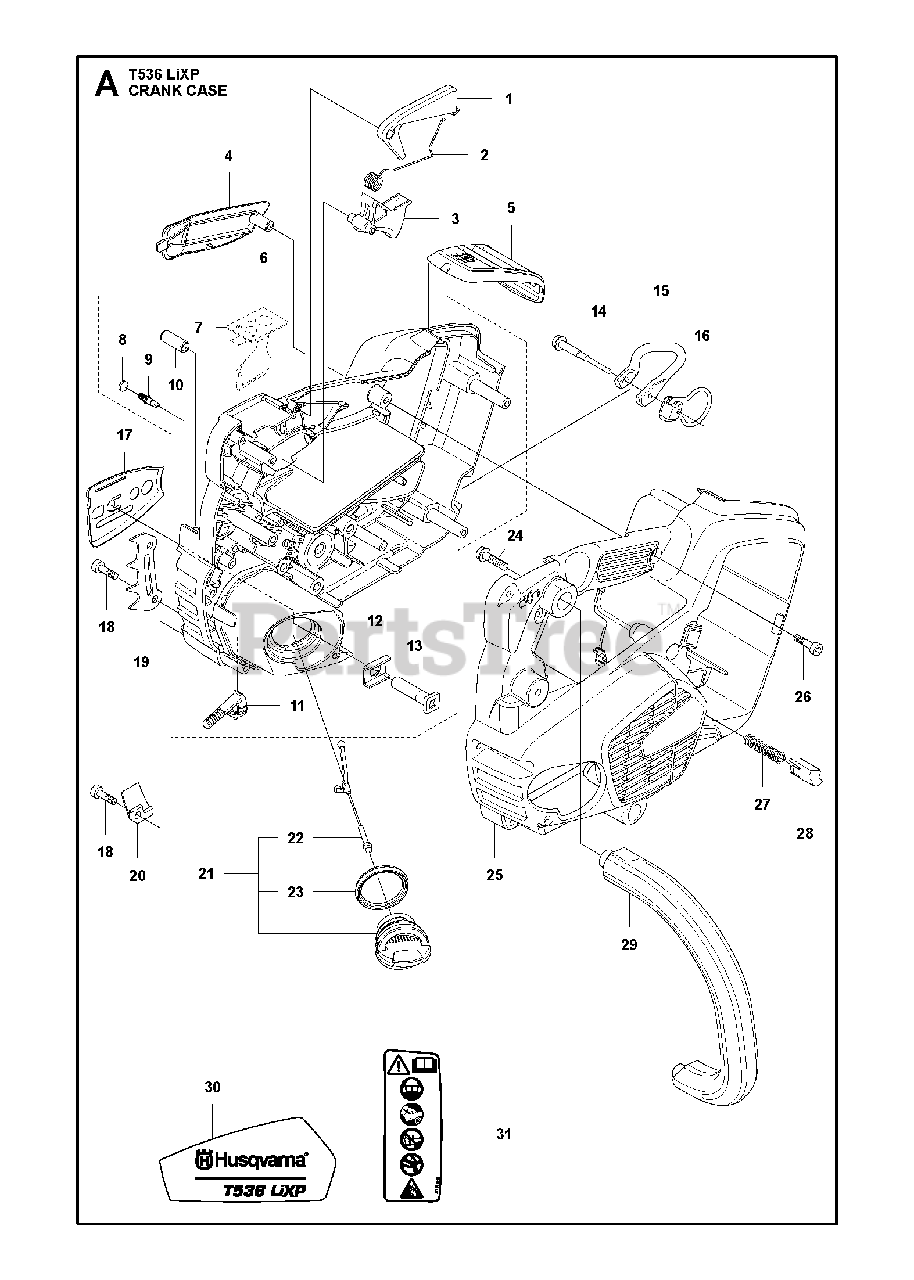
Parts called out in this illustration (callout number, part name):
1	THROTTLE LOCKOUT
3	THROTTLE CONTROL
4	HANDLE INSERT
6	CRANKCASE ASSY
7	KEY PAD
8	PLUG
9	VALVE-CHECK (DUCKBILL)
10	GUIDE BAR LOCATING PIN
11	OIL SCREEN
12	PLATE
13	BOLT
14	SCREW ITXSCFM
16	LOOP
17	CHAIN GUIDE
19	INDRE BARKSTØD
20	CHAIN CATCHER
21	TANK CAP ASSY
22	TANK LOCK
23	SEALING
24	SCREW IHSCFT
25	CRANKCASE
26	SCREW IHSCT MT4X18 10.9 ZN/FE
27	SPRING PUSH OUT
28	PUSH BUTTON
29	FRONT HANDLE
